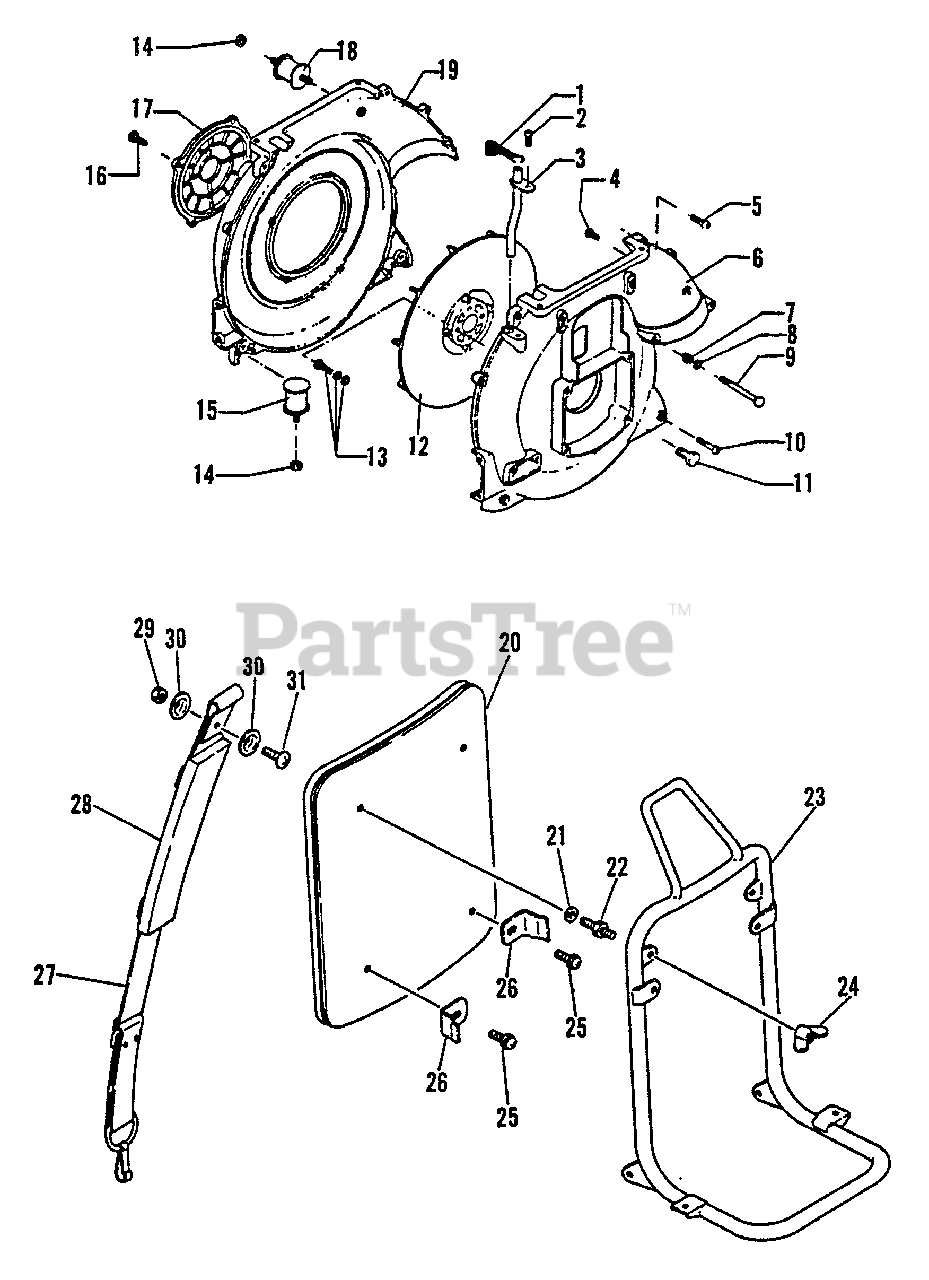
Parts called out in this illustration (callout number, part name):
2	SCREW - 5X10
3	HOSE, AIR
4	SCREW - 4X8
5	SCREW - 5X20
6	COVER, FAN - OUTER
7	NUT - 5
8	WASHER - 5
9	BOLT, ELBOW
10	SCREW - 5X25
11	BOLT - 6X20
13	BOLT - 5X16
14	NUT - 6 -- FLANGE
16	BOLT - 6X14
17	GUARD, DEBRIS
19	COVER, FAN - INNER
20	PLATE, CUSHION
22	STUD
23	FRAME, BACKPACK
24	WINGNUT - 5
25	SCREW - 5X10
26	BRACKET, CUSHION
27	STRAP, BACKPACK
28	PAD, STRAP
29	LOCKNUT - 5
31	SCREW - 5X14
